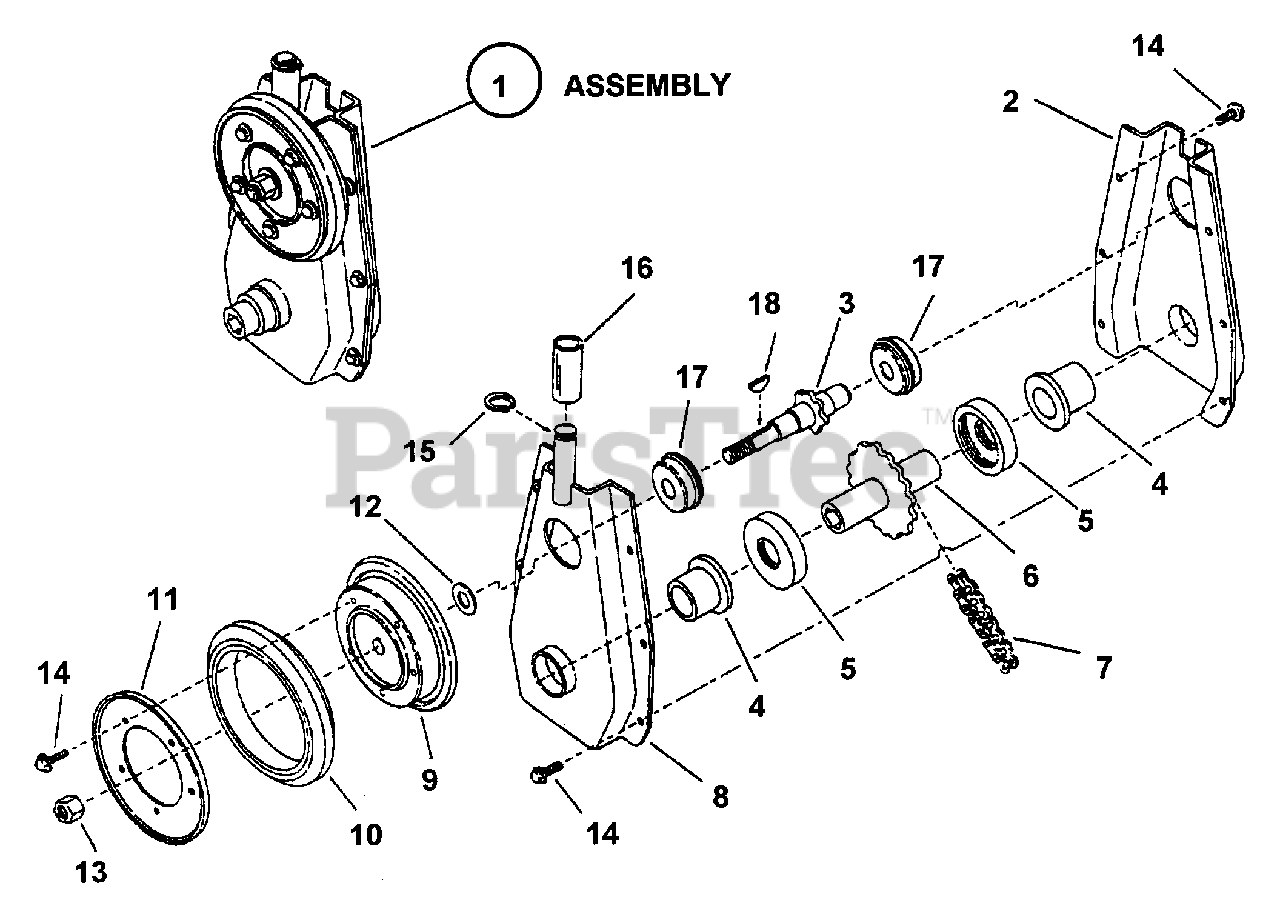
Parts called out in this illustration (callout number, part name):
1	ASSEMBLY, Chain Case
2	ASSEMBLY, Cover Sprocket
3	SHAFT & SPROCKET
4	BEARING
6	HUB & SPROCKET
7	CHAIN
8	ASSEMBLY, Sprocket Case
9	HUB, Driven Disc
10	RING, Driven (Rubber Disc)
11	PLATE
12	WASHER, 3/8" Flat
13	NUT, 3/8-24 Hex Top Lock, Grade C
14	SCREW, #10-24 x 1/2" Hex Washer Self-Tap (Torx)
15	RING, 1/2" External Retaining (Heavy Duty)
16	ROLLER
17	BEARING, Ball
18	KEY, 3/32 x 1/2" Woodruff
